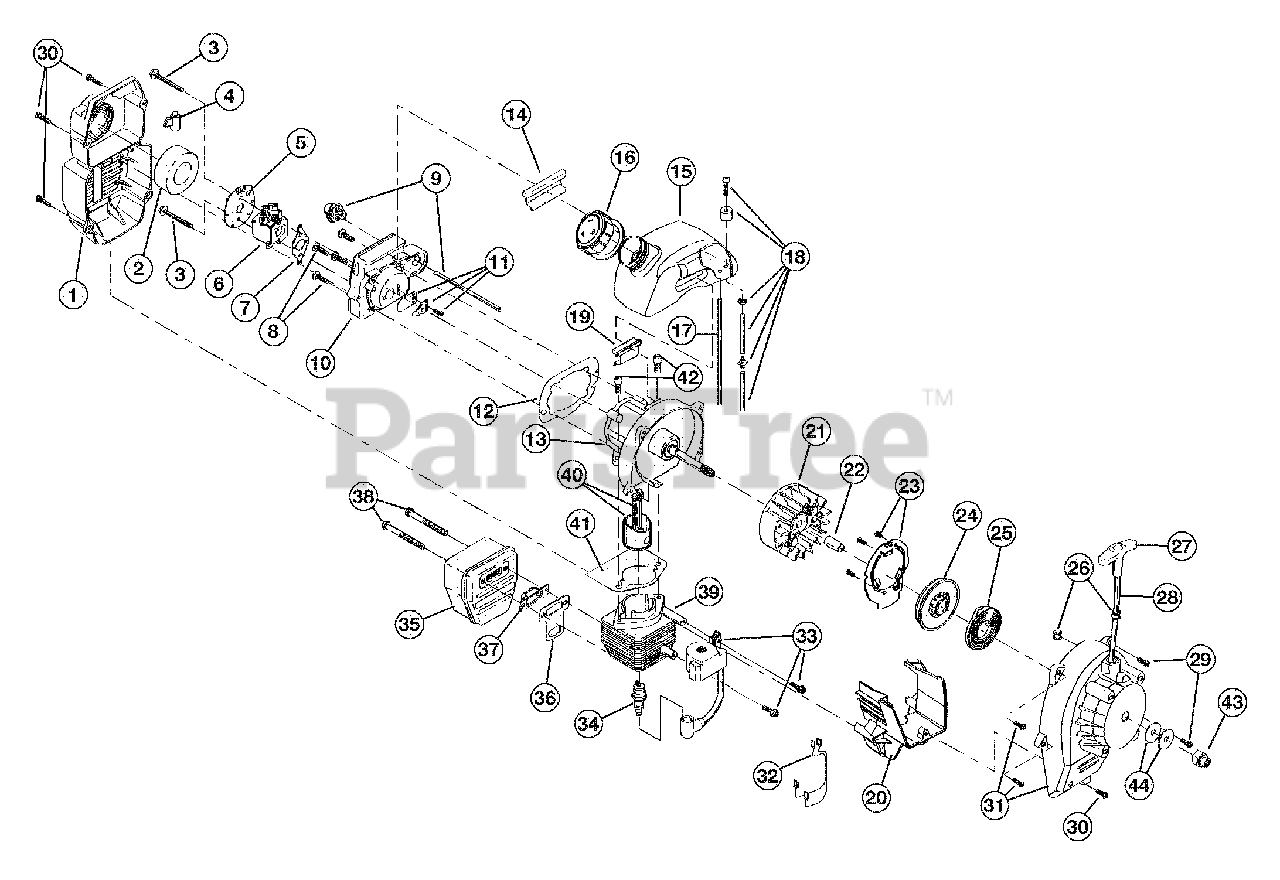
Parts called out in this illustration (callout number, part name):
1	Muffler Cover Assembly
2	Air Cleaner Filter
3	Carburetor Mounting Screw
4	Choke Knob
5	Choke Plate
6	Carburetor Assembly
7	Carburetor Gasket
8	Carb Mount Screw
9	Primer and Hose Assembly
10	Carb Mount Assembly
11	Reed Assembly
12	Carburetor Mount Gasket
13	Crankcase Service Assembly
14	Rear Mounting Pad
15	Fuel Tank Assembly
16	Fuel Cap Assembly
17	Fuel Return Line
18	Fuel Line Assembly
19	Front Mounting Pad
20	Shroud Extension
21	Flywheel Assembly
22	Spacer
23	Pulley Retainer Assembly
24	Recoil Pulley Assembly
25	Recoil Spring
27	Pull Handle
29	Housing Screw
30	Cover Screw
31	Starter Housing Assembly
32	Wire Lead Assembly
33	Module Assembly
35	Muffler Assembly
36	Exhaust Gasket
37	Spark Arrestor
38	Muffler Mounting Bolt
39	Cylinder Assembly
40	Piston and Rod Assembly
41	Cylinder Gasket
42	Cylinder Bolt
43	Crankshaft Extension
44	Washer
